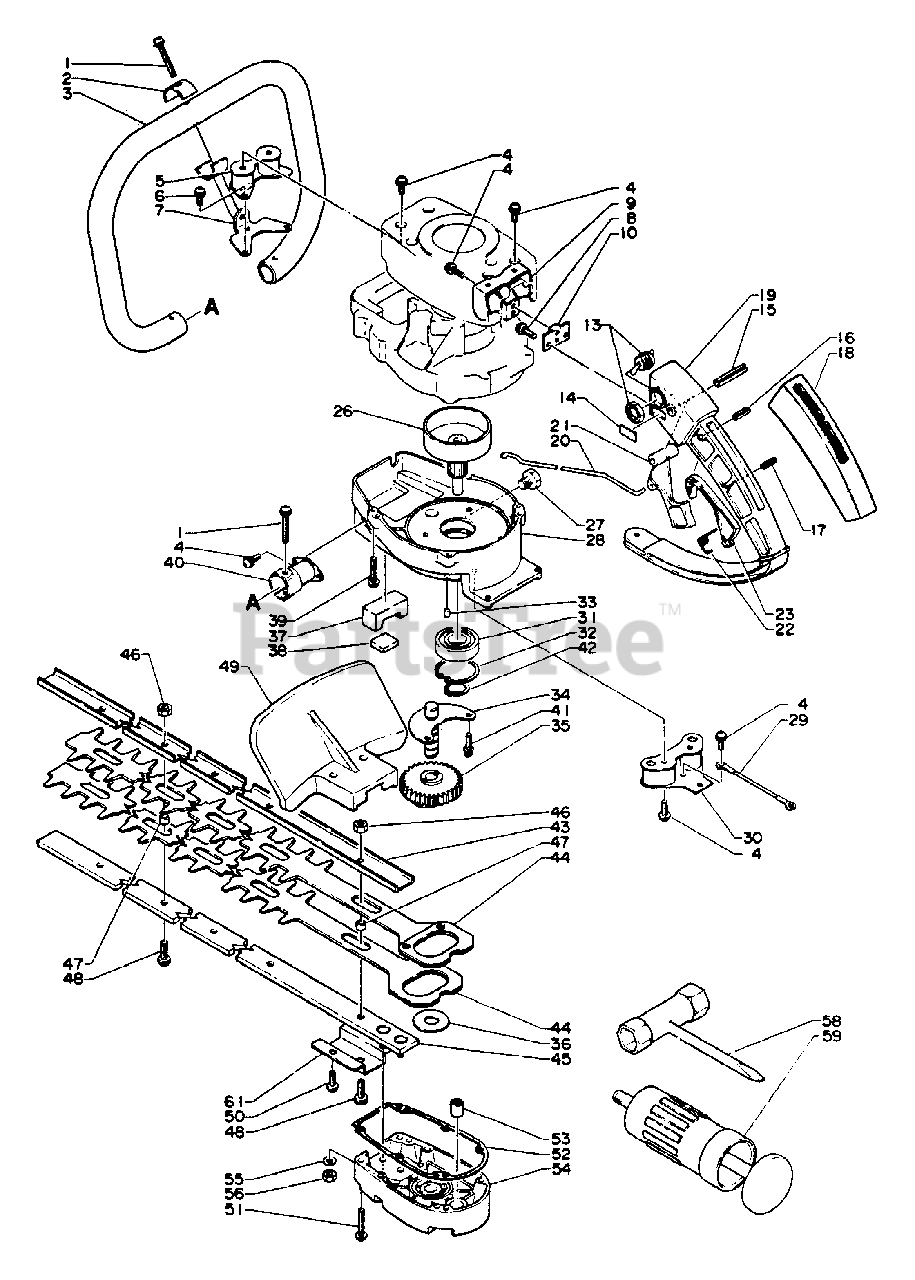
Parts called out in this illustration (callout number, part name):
1	SCREW - 4X30
3	HANDLE - FRONT
4	SCREW - 4X12
6	SCREW - 4X8
7	BRACKET, HANDLE
8	SCREW - 4X12
10	PLATE
13	IGNITION SWITCH KIT
14	LABEL - STOP
15	PIN - SPRING -- 5X32
16	PIN - SPRING -- 4X16
17	PIN - SPRING -- 3X14
19	HANDLE
20	ROD, THROTTLE
21	TRIGGER, THROTTLE
23	LOCKOUT, THROTTLE
26	DRUM, CLUTCH
27	BOLT - 8X8
28	CASE, GEAR
29	LEAD - GROUND
30	CUSHION
31	BEARING, BALL - 6003
32	RING, RETAINING - 35
33	PIN - LOCATING
34	SHAFT GEAR ASSY
35	GEAR SHAFT ASSY
36	SEAT, CAM
37	SEAL, FELT
38	SEAL, FELT
39	SCREW - 4X22
40	CUSHION
41	SCREW - 4X14
42	RING, RETAINING - 16
43	SUPPORT, BLADE
44	TRIMMER BLADE SET
44	BLADE
45	SUPPORT, BLADE - LOWER
46	LOCKNUT - 5
47	SPACER
48	SCREW - 5X18
49	GUARD
50	SCREW - 5X12
51	SCREW - 4X25
52	GASKET, GEAR CASE
53	BEARING, NEEDLE
54	LID, GEAR CASE
55	WASHER - 5
56	LOCKNUT - 5
58	T-WRENCH
59	PUMP, GREASE
61	BRACKET
